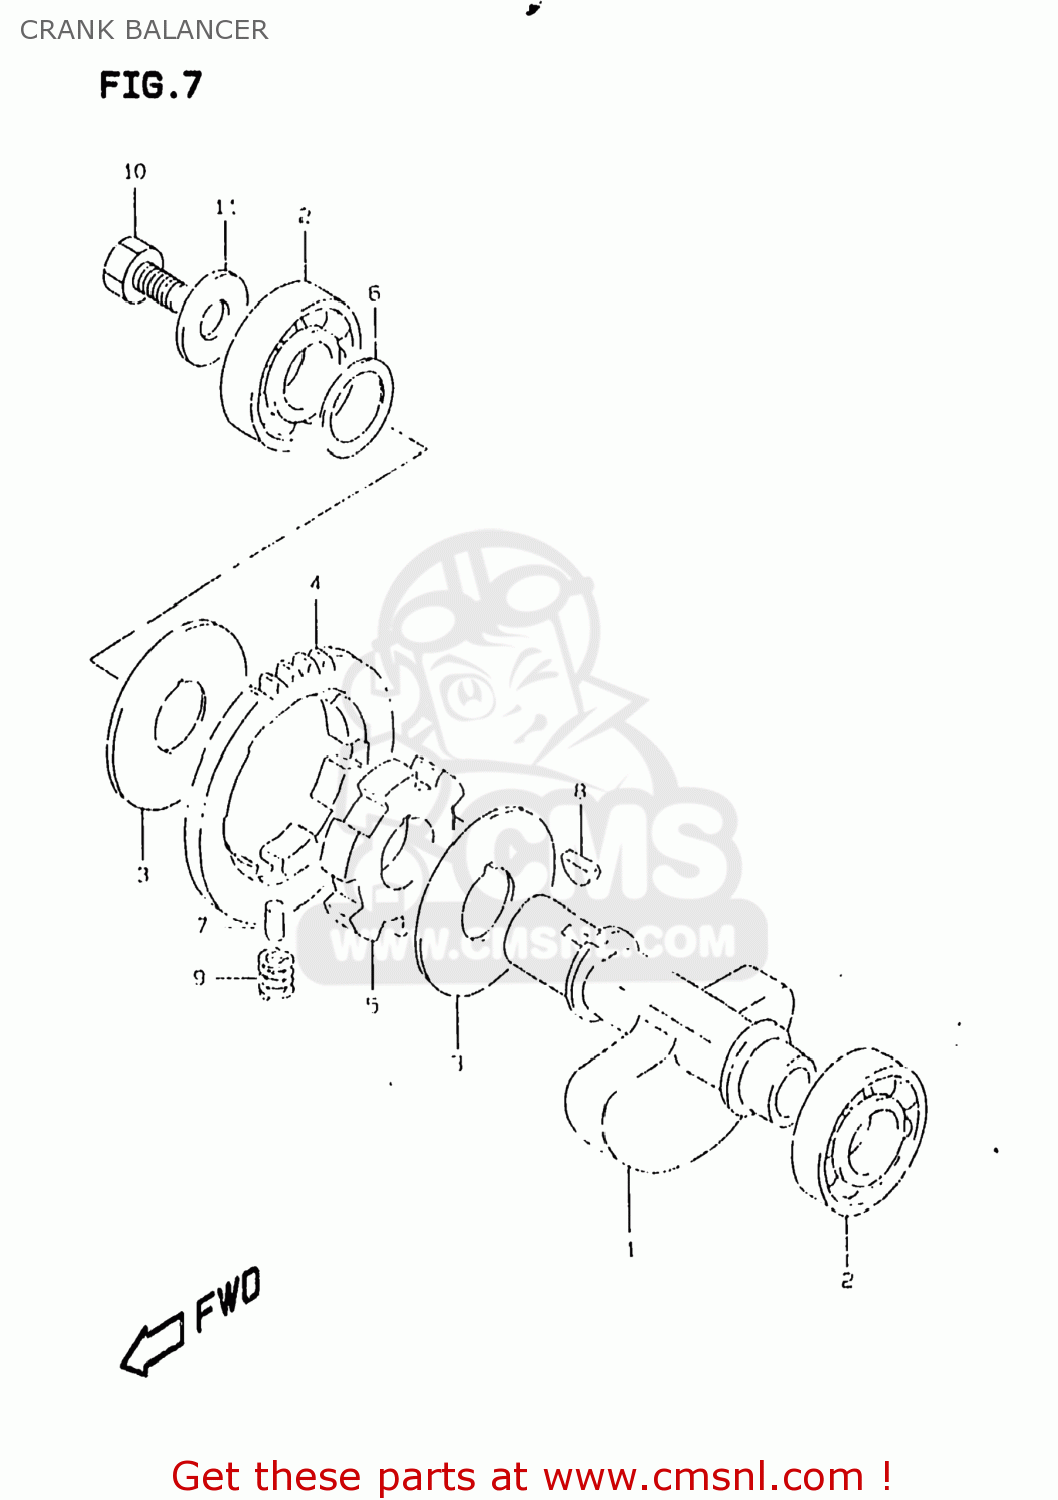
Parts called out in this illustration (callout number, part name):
1	SHAFT,CRANK BALANCER
2	BEARING(20X47X14)
3	WASHER
4	GEAR,CRANK BAL DRIVEN(NT:37)
5	RACE,CRK BAL DRIVEN GEAR INNER
6	SHIM(20X28X0.5)
7	PIN(4.5X9.5)
8	KEY
9	SPRING
10	BOLT
11	WASHER
